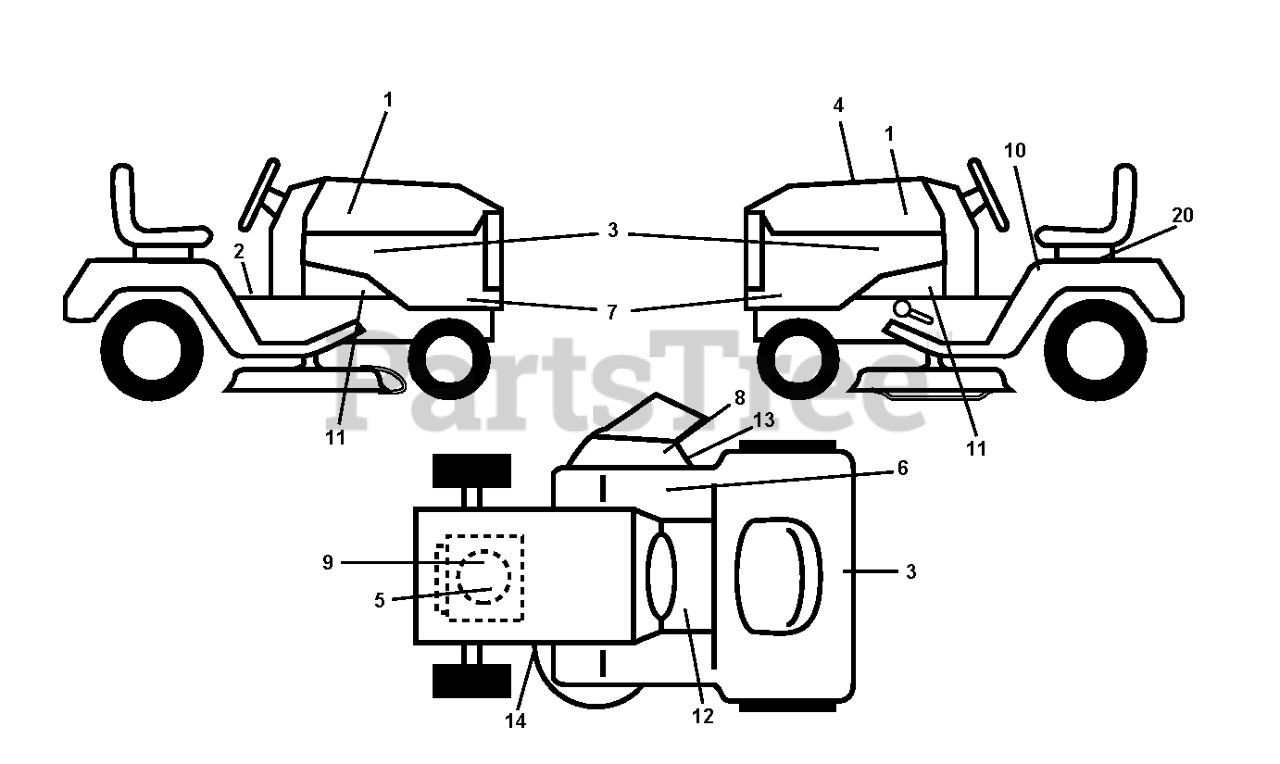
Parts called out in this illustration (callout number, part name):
2	DECAL PARK BRAKE
3	DECAL.HOOD.LOGO.ORANGE.HUSQVAR
5	DECAL
6	Decal, Fender 100 DB/CE
8	DECAL.INTERNATIONL.CUTFINGER
9	DECAL
10	LABEL
12	DECAL
13	DECAL, DEFLECT WARNING
14	DECAL.V-BELT.SCHEMATIC.36/38/9
20	DECAL BTRY SYMBOLS
